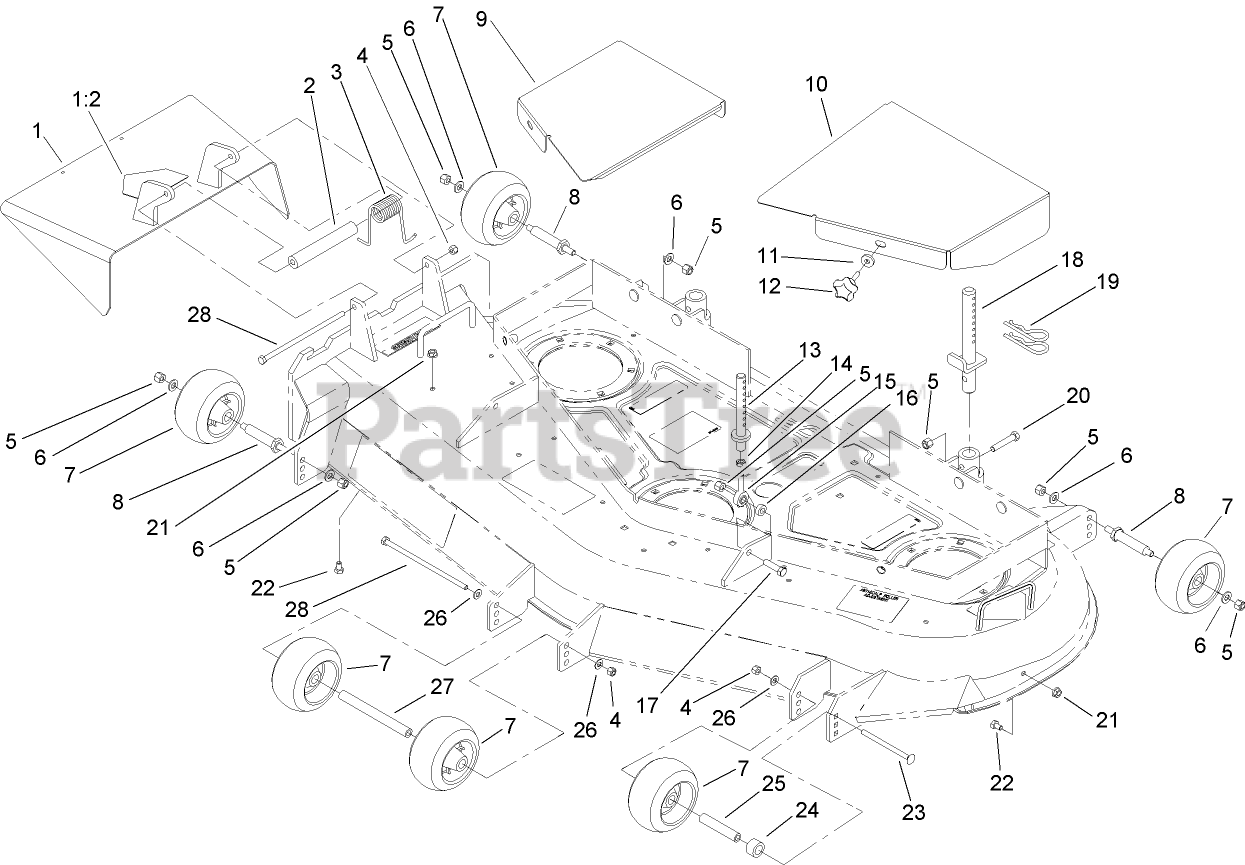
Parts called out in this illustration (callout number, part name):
1	Deflector ASM
1:2	DECAL-DANGER
2	SPACER
3	SPRING-TORSION
4	NUT-LOCK, NI
5	NUT-LOCK, NI
6	WASHER-FLAT
7	WHEEL-GAGE
8	SPACER
9	COVER-BELT, RH
10	COVER-BELT, LH
11	WASHER-RUBBER
13	FRONT PIN ASM
14	NUT-HJ
15	BALLJOINT
16	SPACER
17	SCREW-HH
18	REAR PIN ASM
19	PIN-HAIR
20	SCREW-HH
21	NUT-HF
22	SCREW-HH
23	SCREW-CARR
24	SPACER-WHEEL
25	BUSHING-ROLLER
26	WASHER-PLAIN
27	SPACER-WHEEL
28	SCREW-HH
